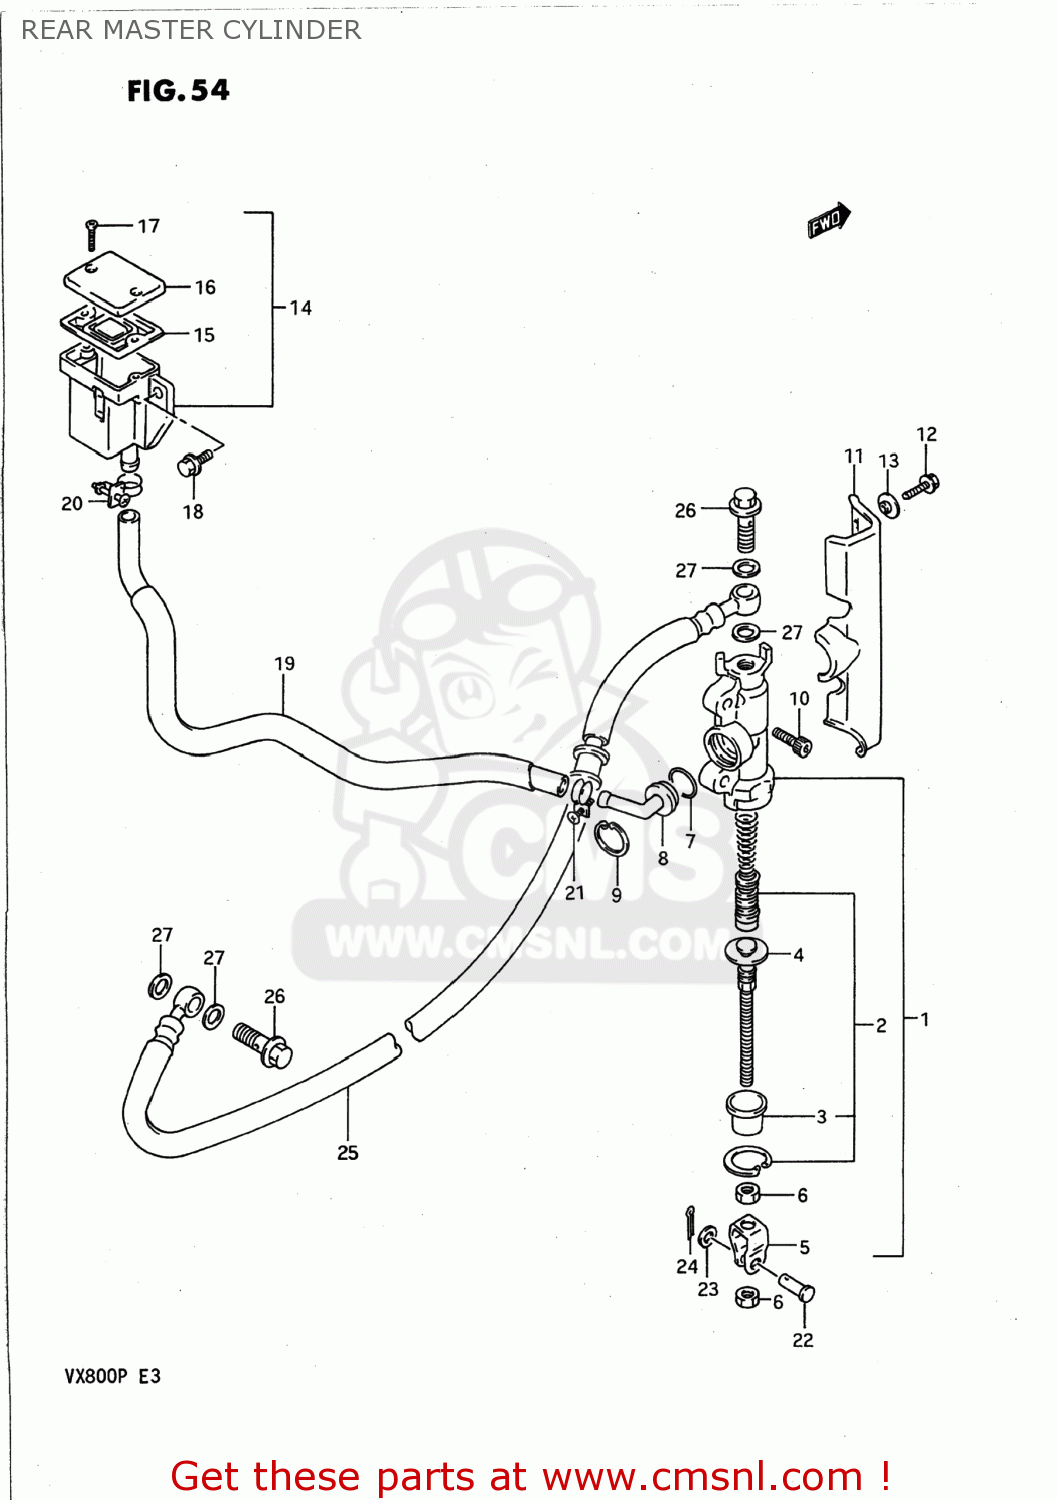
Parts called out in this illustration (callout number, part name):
1	CYLINDER ASSEMBLY,REAR MASTER
2	PISTON/CUP SET
3	BOOT
4	ROD,PUSH
5	YOKE
6	NUT
7	O RING
8	CONNECTOR
9	CIRCLIP
10	BOLT
11	COVER,FRAME MASTER CYLINDER
12	SCREW 6X12
13	WASHER
14	TANK ASSY,RESERVOIR
15	DIAPHRAGM
16	CAP
17	SCREW
18	BOLT
19	HOSE,RESERVOIR TANK
20	CLAMP
21	CLAMP
22	PIN
23	WASHER
24	PIN
25	HOSE,RR BRAKE
26	BOLT,UNION
27	WASHER(10X15X1.5)
